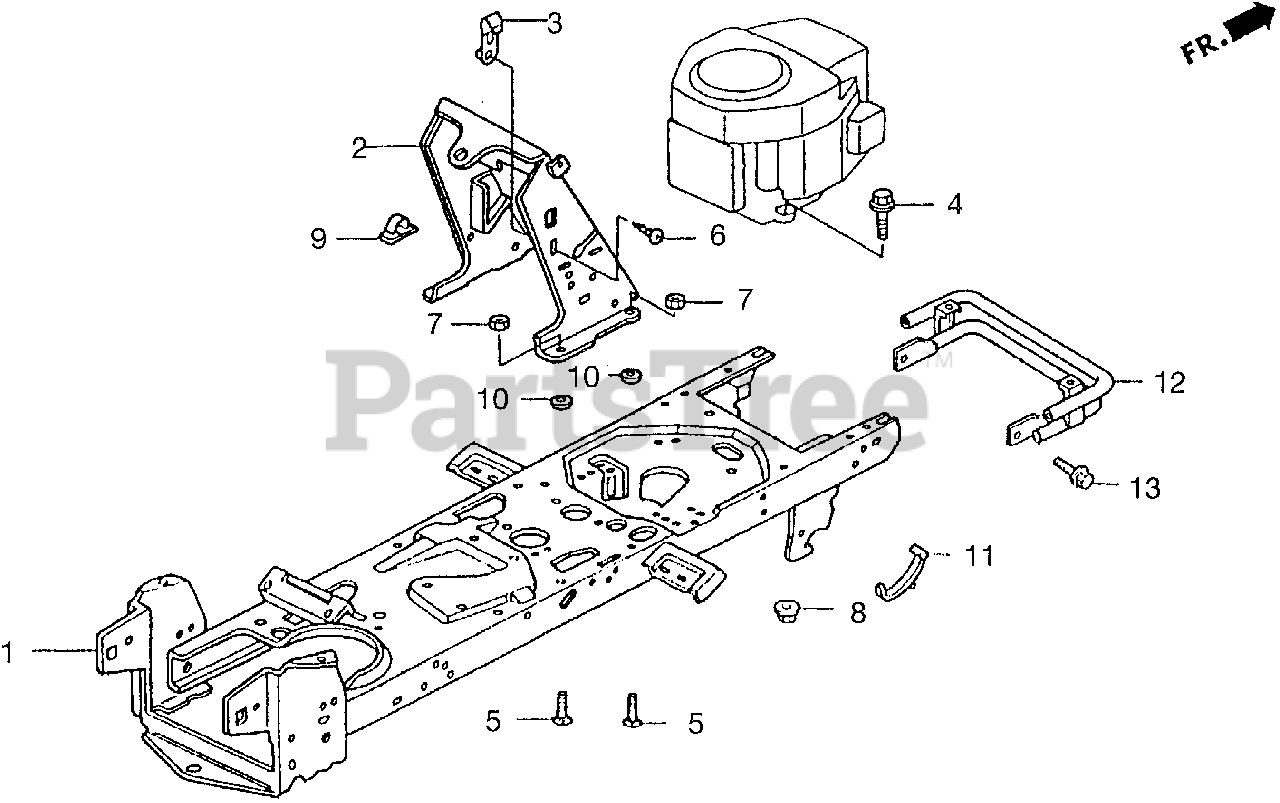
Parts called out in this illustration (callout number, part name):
1	FRAME, MAIN
2	COLUMN, STEERING
3	LOCK, HOOD
4	BOLT, FLANGE (8X45)
5	BOLT, CARRIAGE (8X16)
6	SCREW B, TAPPING
7	NUT, FLANGE (8MM)
8	NUT A, LOCK (8MM)
9	CLIP, WIRE
10	RETAINER, FRAME
11	TIE, DRAIN HOSE
12	GUARD, FR.
13	BOLT, FLANGE (8X16) (19M7867)
